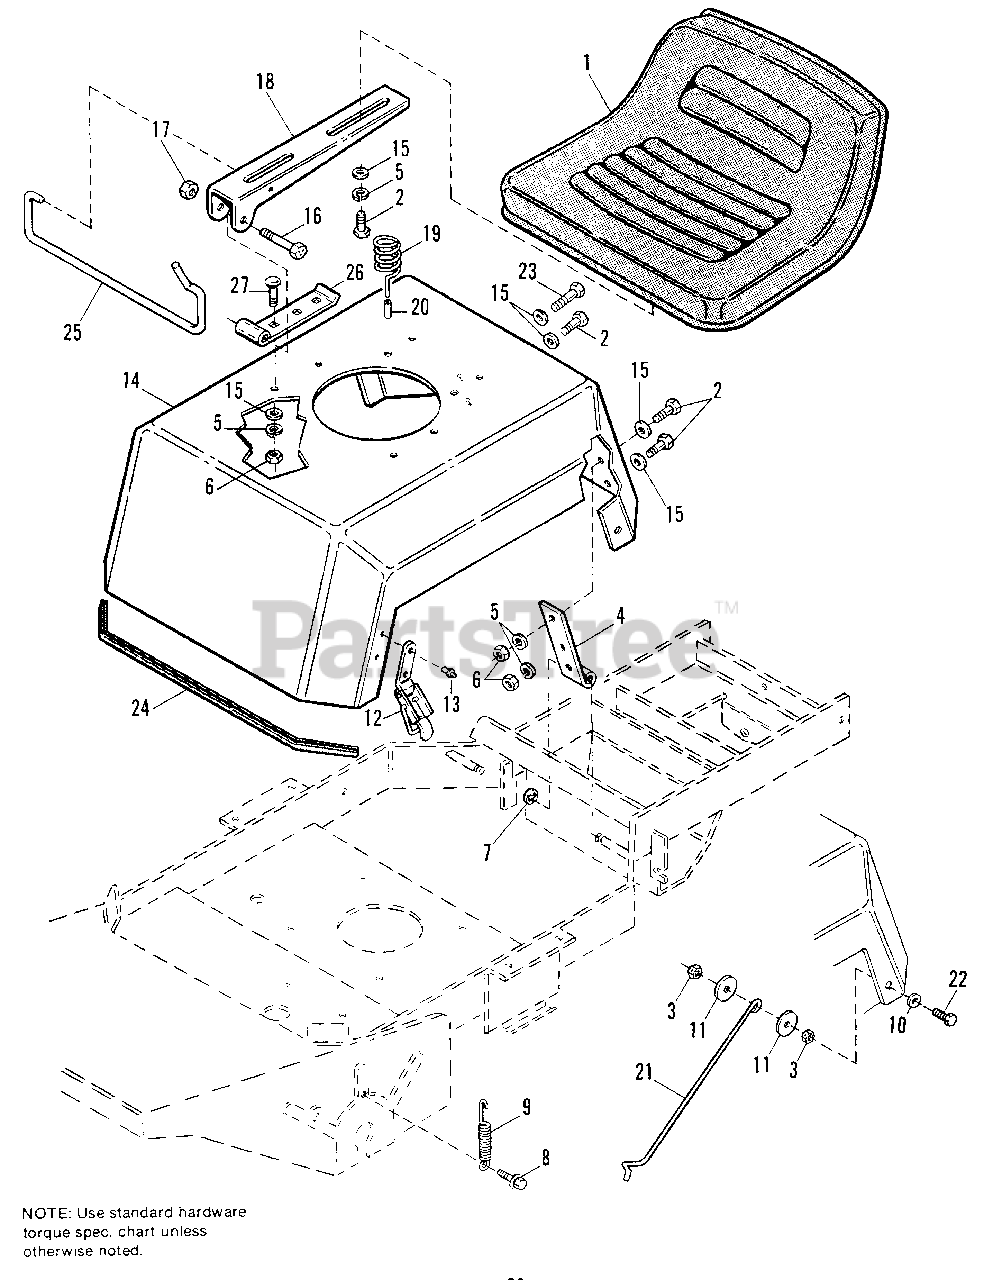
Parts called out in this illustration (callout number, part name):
2	CAPSCREW, 5/16-18 x 3/4
3	NUT, Hex Centerlock, 1/4-20
4	HINGE, Seat Deck
5	LOCKWASHER, 5/16
6	NUT, Hex, 5/16-18
7	RING, Retaining
8	SCREW, Taptite, 5/16-18 x 1/2
9	SPRING, Latch
10	WASHER, 1/4 x 3/4
11	WASHER, 1/4 x 1-1/4
12	LATCH, Seat, Pull Tight
13	RIVET, Seat Latch
15	WASHER, Flat, 5/16
16	CAPSCREW, 3/8-16 x 2
17	NUT, Hex Lock, 3/8-16
18	HINGE, Upper, Seat
19	SPRING, Seat
20	COVER, Spring
21	ROD, Seat Deck
22	CAPSCREW, Hex, 1/4-20 x 1
23	CAPSCREW, Hex, 5/16-18 x 1
24	MOULDING, Deck
25	LATCH, Seat
26	HINGE, Lower
27	BOLT, Carriage, 5/16-18 x 3/4
